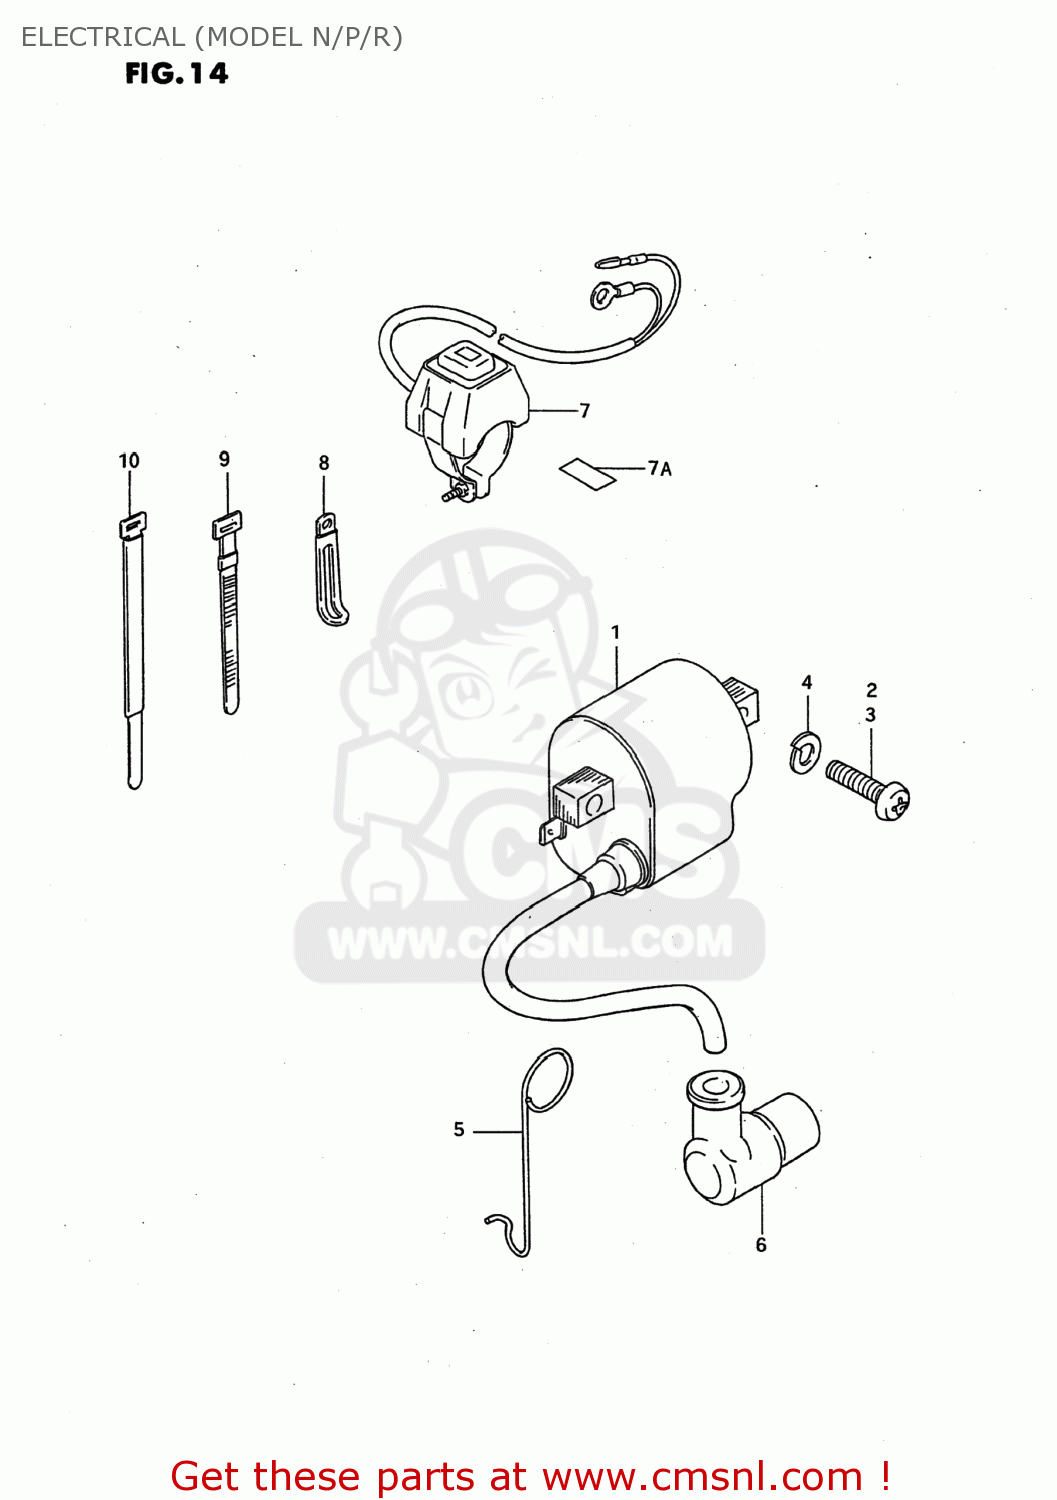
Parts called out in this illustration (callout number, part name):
1	COIL ASSEMBLY,IGNITION
2	SCREW
3	SCREW
4	WASHER,LOCK
5	CLIP
6	CAP,SPARK PLUG
7	SWITCH ASSEMBLY
7A	LABEL (ENGINE STOP)
8	CLAMP
9	CLAMP(L:120)
10	CLAMP
